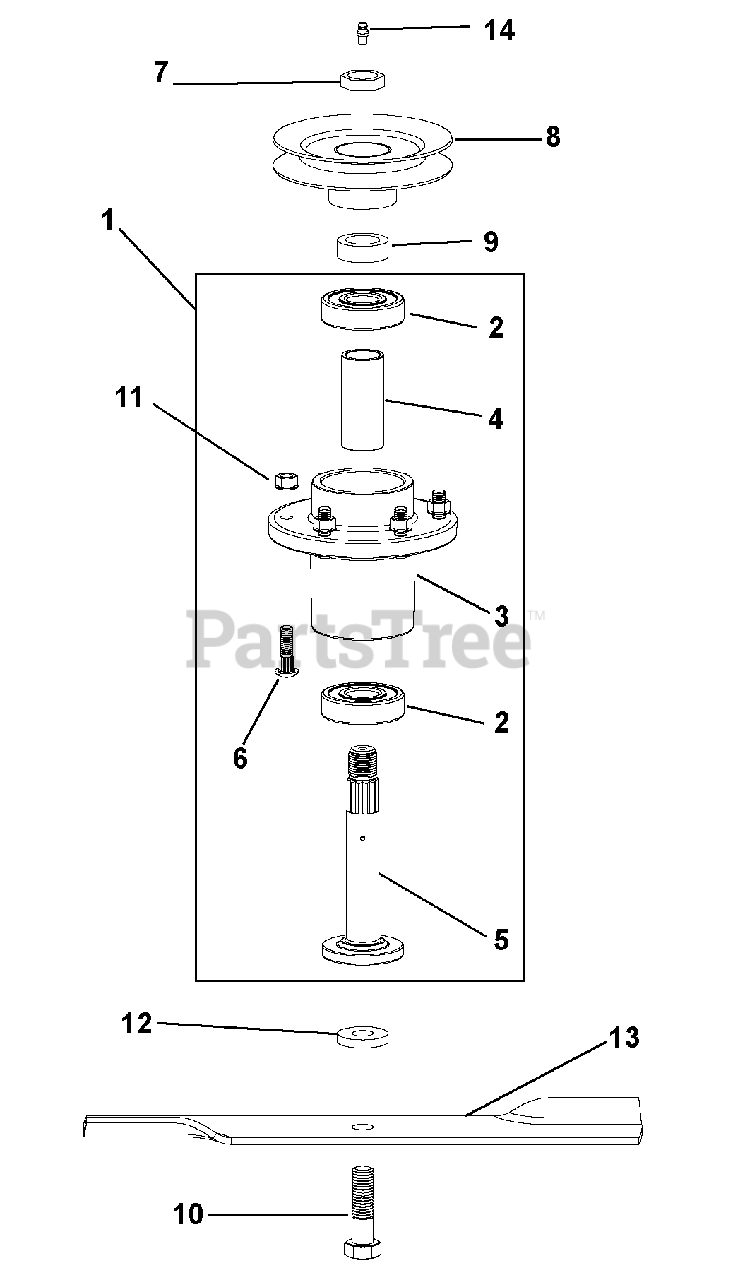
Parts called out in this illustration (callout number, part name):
1	SPINDLE ASSEMBLY, INCLUDES ITE
2	BALL BEARING
3	HOUSING
4	SPACER, 1.000 X 1.250 X 2.772
5	SHAFT, SPINDLE
6	BOLT, 3/8-16 X 1.25 RIB
7	NUT, PULLEY (SPECIAL)
9	SPACER, PULLEY
10	BLT-HEX .62-11X2.25 YWZC GR8
11	@NUT-HEX .31-18 YWZC
12	SPACER, BLADE BOLT
13	BLADE-MOWER 18.00" LOW-LIFT
13	BLADE-MOWER 16.50" LOW-LIFT
14	ZERK, GREASE S/O
